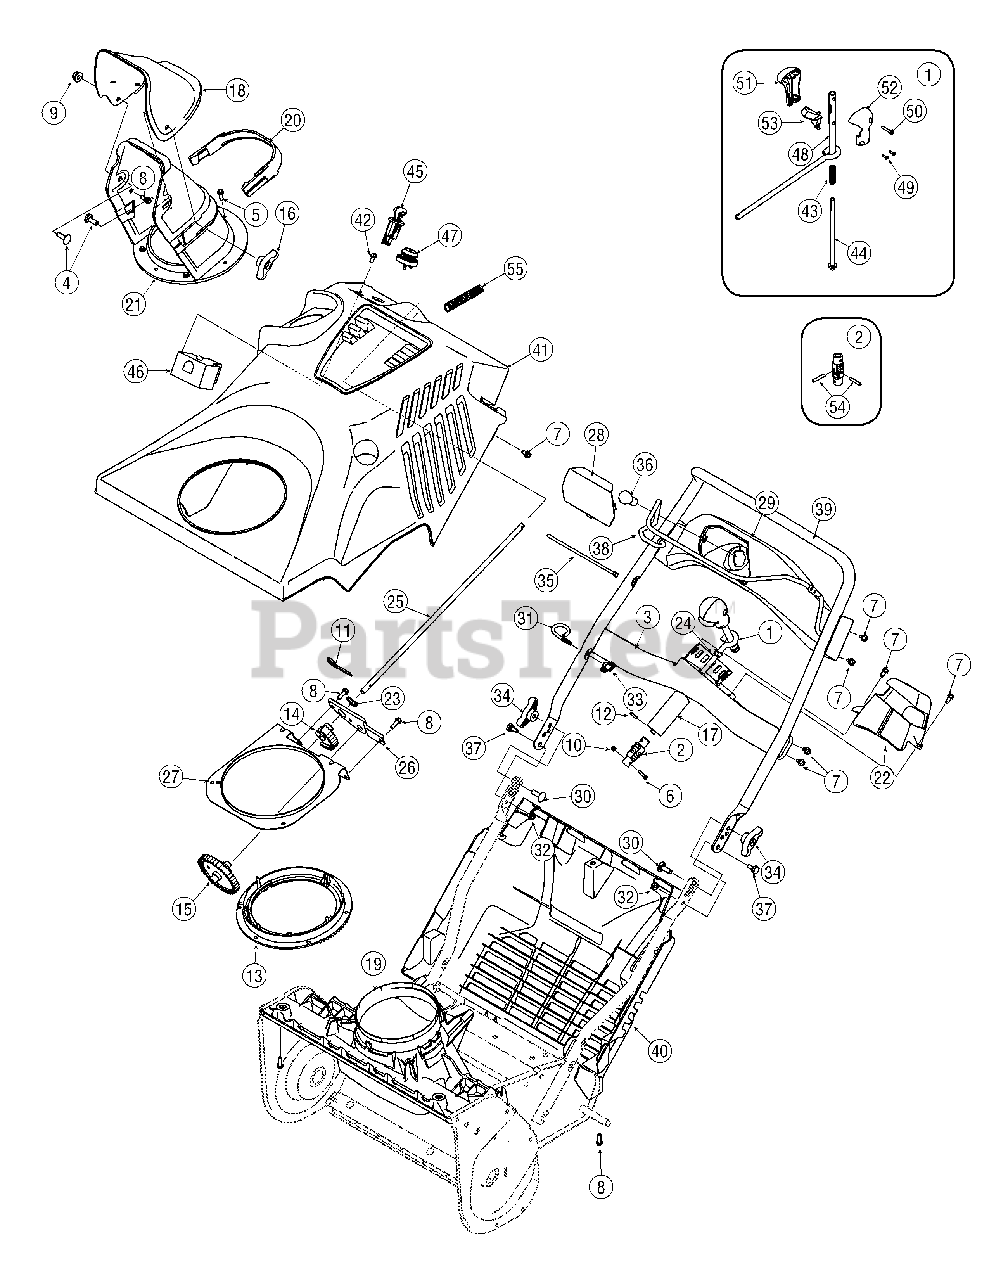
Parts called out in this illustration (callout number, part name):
1	Chute Rotation Control Assembly
2	Joint Block Assembly
3	Indicator Bracket Assembly
4	Carriage Bolt, 5/16-18 x .750
5	Hex Washer Screw, 1/4 x .750
6	Machine Screw, #8-32 x .88
7	Hex Washer Screw, 1/4-20 x 0.500
8	Hex Washer Screw, 1/4-15 x 0.750
9	Flange Lock Nut, 5/16-18
10	Hex Lock Nut, #8-32
11	Cotter Pin, .125 x 2.5
12	Spring Pin, .156 x .85
13	Bevel Gear, 95T
14	Spur Gear, 35T
15	Spur Gear, 40T/11T
16	Wing Knob, 5/16-18
17	Grip, 1.18 x 3.33
18	Upper Chute
19	Chute Adapter
20	Chute Plug
21	Lower Chute
22	Chute Rotation Cover
23	Flat Washer, .75 x 1.00 x .06
24	Plastic Bushing, .380
25	Chute Rotation Rod, 3/8
26	Gear Mounting Plate
27	Gear Retainer Bracket
28	Handle Panel Lens
29	Handle Panel
29	Light Label
30	Carriage Screw, 5/16-18 x 1.00
31	Eye Bolt, 1/4-20
32	Flange Lock Nut, 1/4-20
33	Wing Knob, 1/4-20
34	Wing Knob, 5/16-18
35	Cable Tie, 3/16 x .05 x 7.4
36	Lamp, #1141
37	Shoulder Screw, 1/4-20 x .375 x .148
38	Auger Control
39	Upper Handle
40	Bottom Cover Assembly
41	Cover Assembly
42	Hex Washer Screw, 1/4-15 x .50
43	Compression Spring, .460 x 1.469
44	Chute Rotation Rod
45	Ignition Switch Assembly
46	Electric Starter
48	Chute Rotation Rod Assembly
49	Screw, #6 x .375
50	Screw, #8 x 1.00
51	RH Control Knob
52	LH Control Knob
53	Joystick Trigger
54	Roll Pin, 3/16 x 1.1
55	Conduit
